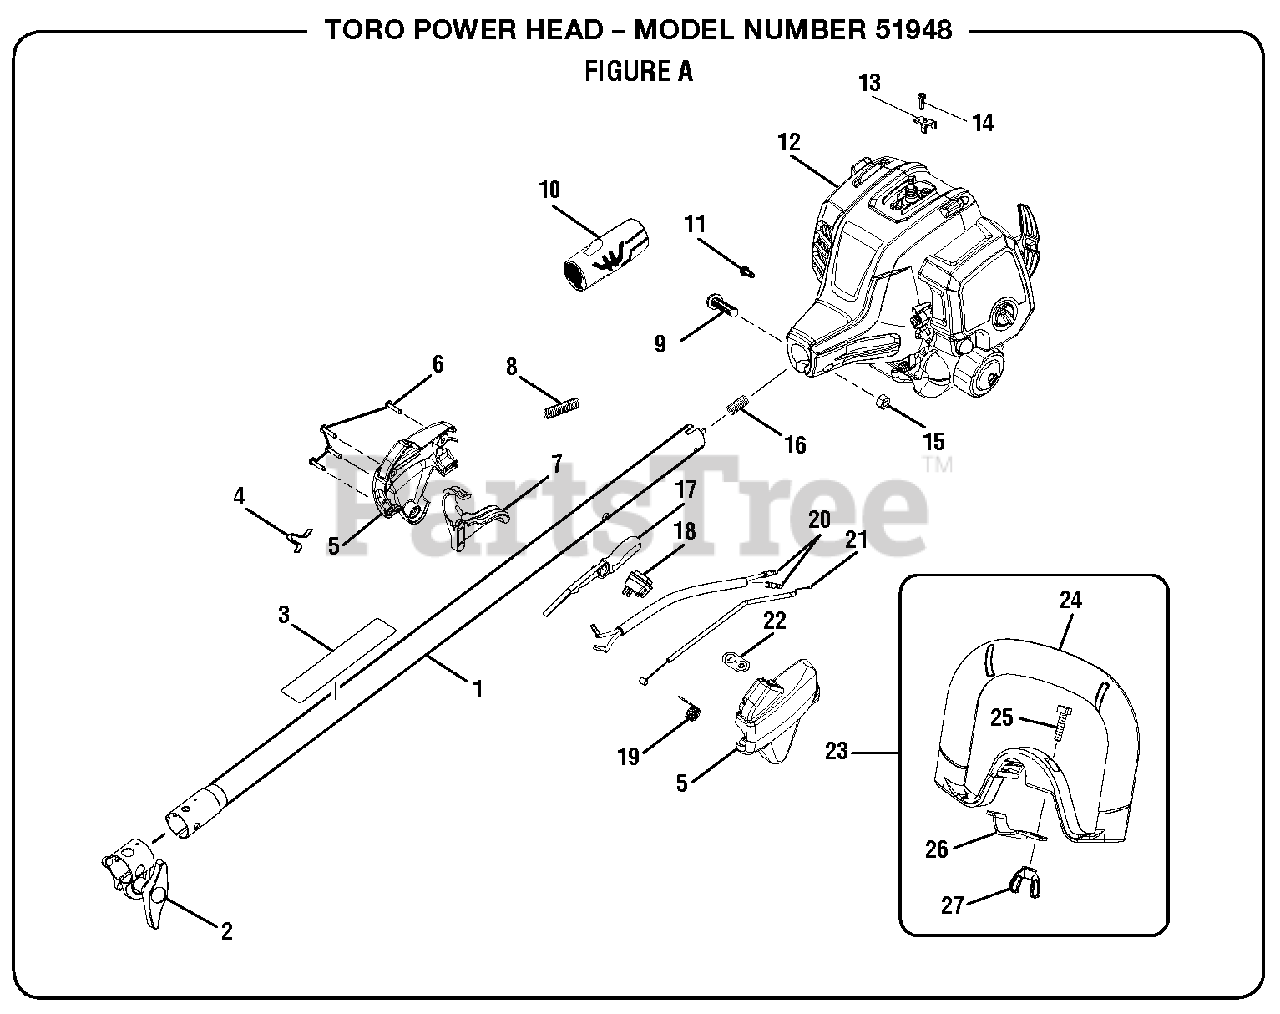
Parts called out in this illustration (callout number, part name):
1	Upper Boom Assembly
2	Boom Clamp Assembly
3	Warning Label
4	Shoulder Strap Clip
5	Control Handle Assembly
6	Screw (M4 x 20 mm, T20 Torx Hd.)
8	Corrugated Tube
9	Screw (M6 x 30 mm)
10	Rear Handle Grip
11	Screw (M4 x 8 mm, T20 Torx Hd.)
12	Powerhead Assembly
13	Throttle Cable Clamp
14	Screw (M4 x 16 mm)
15	Hex Nut (M6.3 x 1)
16	Compression Spring
17	Trigger Lock
18	On/Stop Switch
19	Throttle Cable Spring
20	Lead Assembly
21	Throttle Cable
22	On/Stop Label
23	Front Handle Assembly
24	Front Handle w/Grip
25	Screw (1/4-20 x 1 in., Sq. Hd.)
26	Front Handle Clamp
27	Wing Nut (1/4-20)
